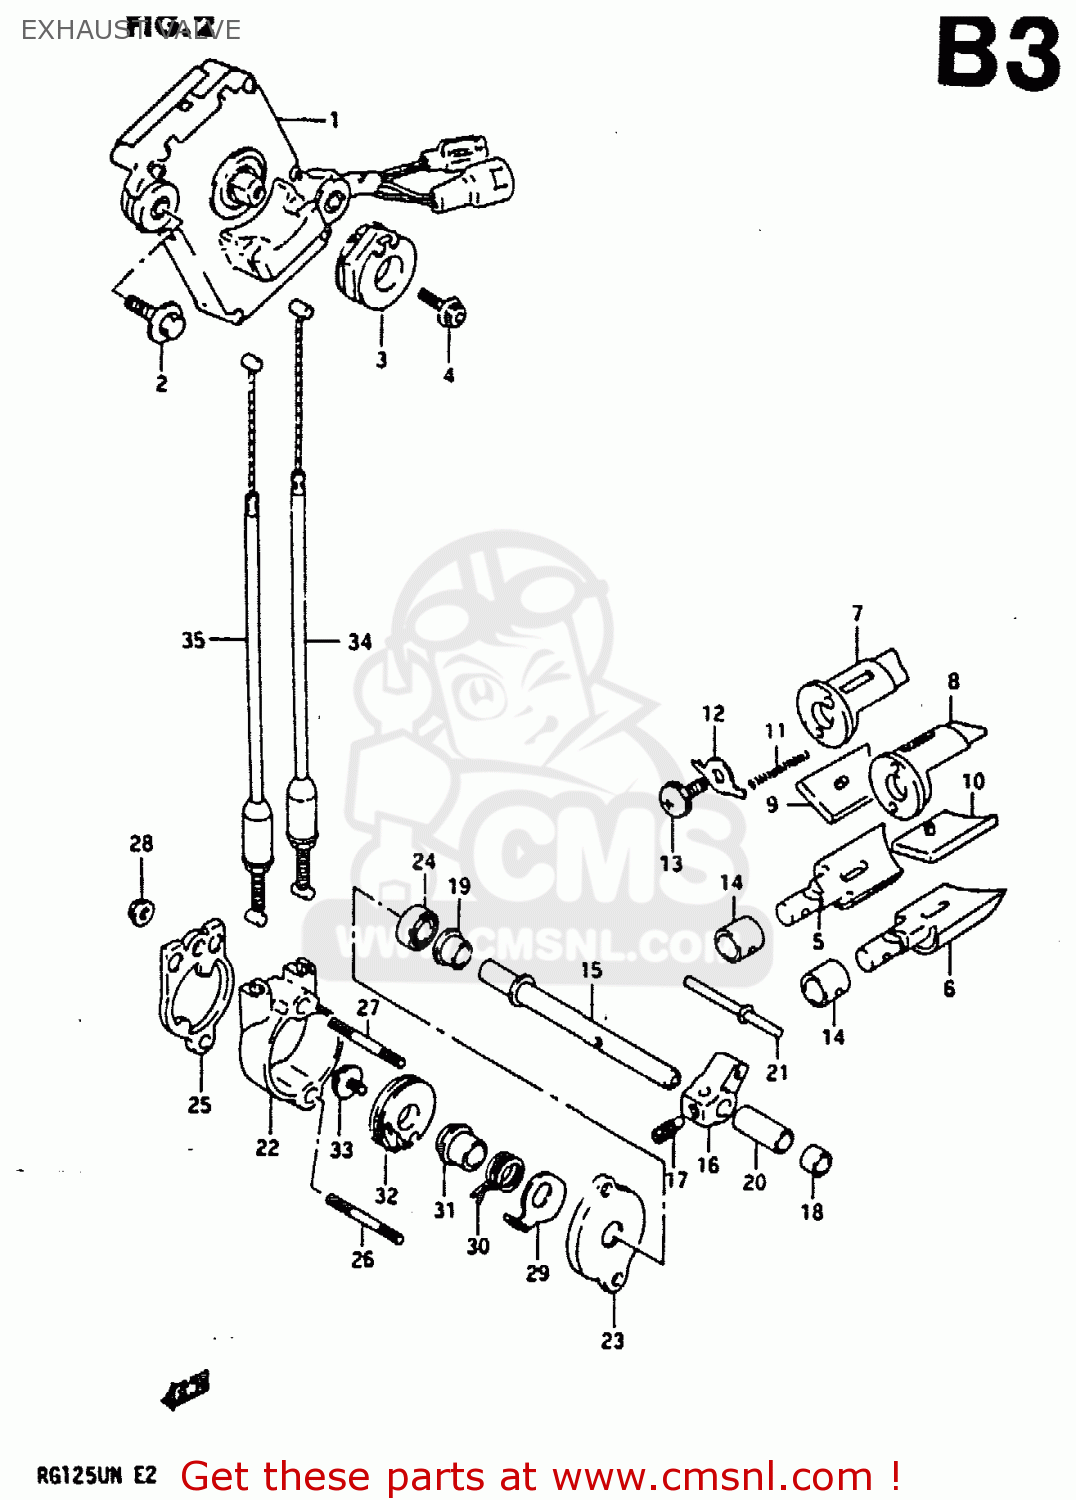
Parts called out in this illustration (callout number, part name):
1	ACTUATOR ASSY, EXHAUST VALVE
2	BOLT(6X25)
3	PULLEY,CONTROLLER
4	BOLT
5	VALVE,EXHAUST LWR,R
6	VALVE,EXHAUST LWR,L
7	GUIDE, EXHAUST VALVE RH
8	GUIDE, EXHAUST VALVE LH
9	VALVE, EXHAUST MIDDLE RH
10	VALVE, EXHAUST MIDDLE LH
11	SPRING
12	RETAINER,EXHAUST VALVE SPRING
13	SCREW
14	SPACER,EXHAUST VALVE
15	SHAFT,EXHAUST VALVE
16	ARM,EXHAUST VALVE SHAFT
17	SCREW(6X10)
18	BUSH(8X12X7)
19	BUSH,EXHAUST VALVE NO.2
20	SPACER,EXHAUST VALVE SHAFT
21	PIN,EXHAUST VALVE 48.5MM
22	HOLDER, EXHAUST VALVE
23	SPACER, HOLDER BASE
24	SEAL,OIL(8X16X5)
25	COVER, HOLDER
26	STUD BOLT
27	BOLT,STUD
28	NUT
29	LEVER,EXHAUST VALVE
30	SPRING,EXHAUST VALVE LEVER
31	SPACER,EXHAUST VALVE PULLEY
32	PULLEY,EXHAUST VALVE
33	BOLT(5X12)
34	CABLE,EXHAUST VALVE NO.1
35	CABLE,EXHAUST VALVE NO.2
